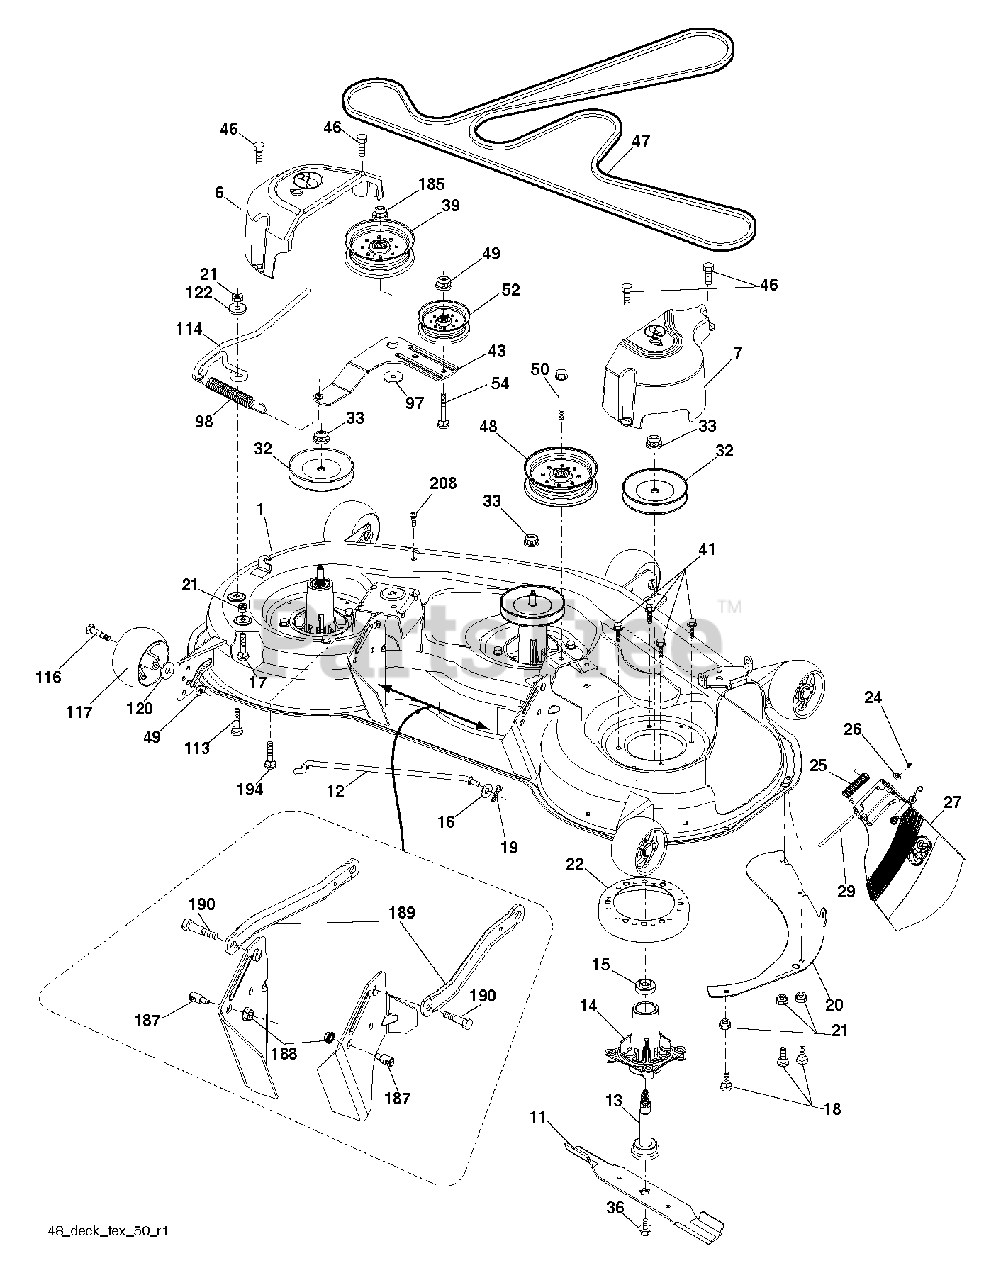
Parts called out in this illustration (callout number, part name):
1	DECK.WELDMENT.48"2006
6	COVER.MANDREL.LH.48"
7	Mandrel Cover, RH 48"
11	48" HI-LIFT BLADE
12	ROD.ANTI.SWAY.48/54"K4
13	Mandrel Assembly, Greaseable
14	HOUSING.MANDREL.4PT.
15	Extended Mandrel Bearing, Top
16	WASHER
17	BOLT
18	BOLT
19	PIN.COTTER.5/16.BOW TI
20	BAFFLE, VORTEX MWR
21	LOCKNUT
22	STRIPPER.MANDREL.ROUND.BLACK
24	CAP-SLEEVE LT
25	SPRING, TORSION
26	NUT PUSH M
29	ROD.HINGE
32	PULLEY MANDREL
33	NUT.FLANGE.LOCK.TOP
36	Screw, 7/16 X 20 X 1"
39	PULLEY.IDLER.4.50/HUB SPECIAL
41	Hex Washer Head Bolt, .313-18 X 1.19
43	ARM.IDLER
46	SCREW.1/4-20X5/8
47	BELT.DRIVE.DECK
48	PULLEY.IDLER.2006
49	NUT LOCK FLG 3/8-16 UNC
50	SCREW TT 3/8-16X2-1/4 UNC
52	PULLEY.IDLER.48"PRIMARY
54	BOLT.3/8-16X1.50
98	SPRING, DECK DRIVE
113	BOLT CRT
114	ROD.TENSION.RELIEF.TEX (2 2)
116	BOLT.SHOULDER.3/8-16X3-5/8.
117	WHEEL. GUAGE RALLY
122	BUSHING.RELIEF.TENSION
185	NUT.LOCK.FLANGE.7/16
187	STUD.FASTNER.W/ANTI-ROTATE
188	NUT LOCK HEX FLANGE 5/16-18
189	ARM.SUSPENSION.MOWER
190	BOLT.SHOULDER
194	BOLT.HEX.WASHER.HEAD.7/16-24X
208	SCREW 3/8-16X1/2
